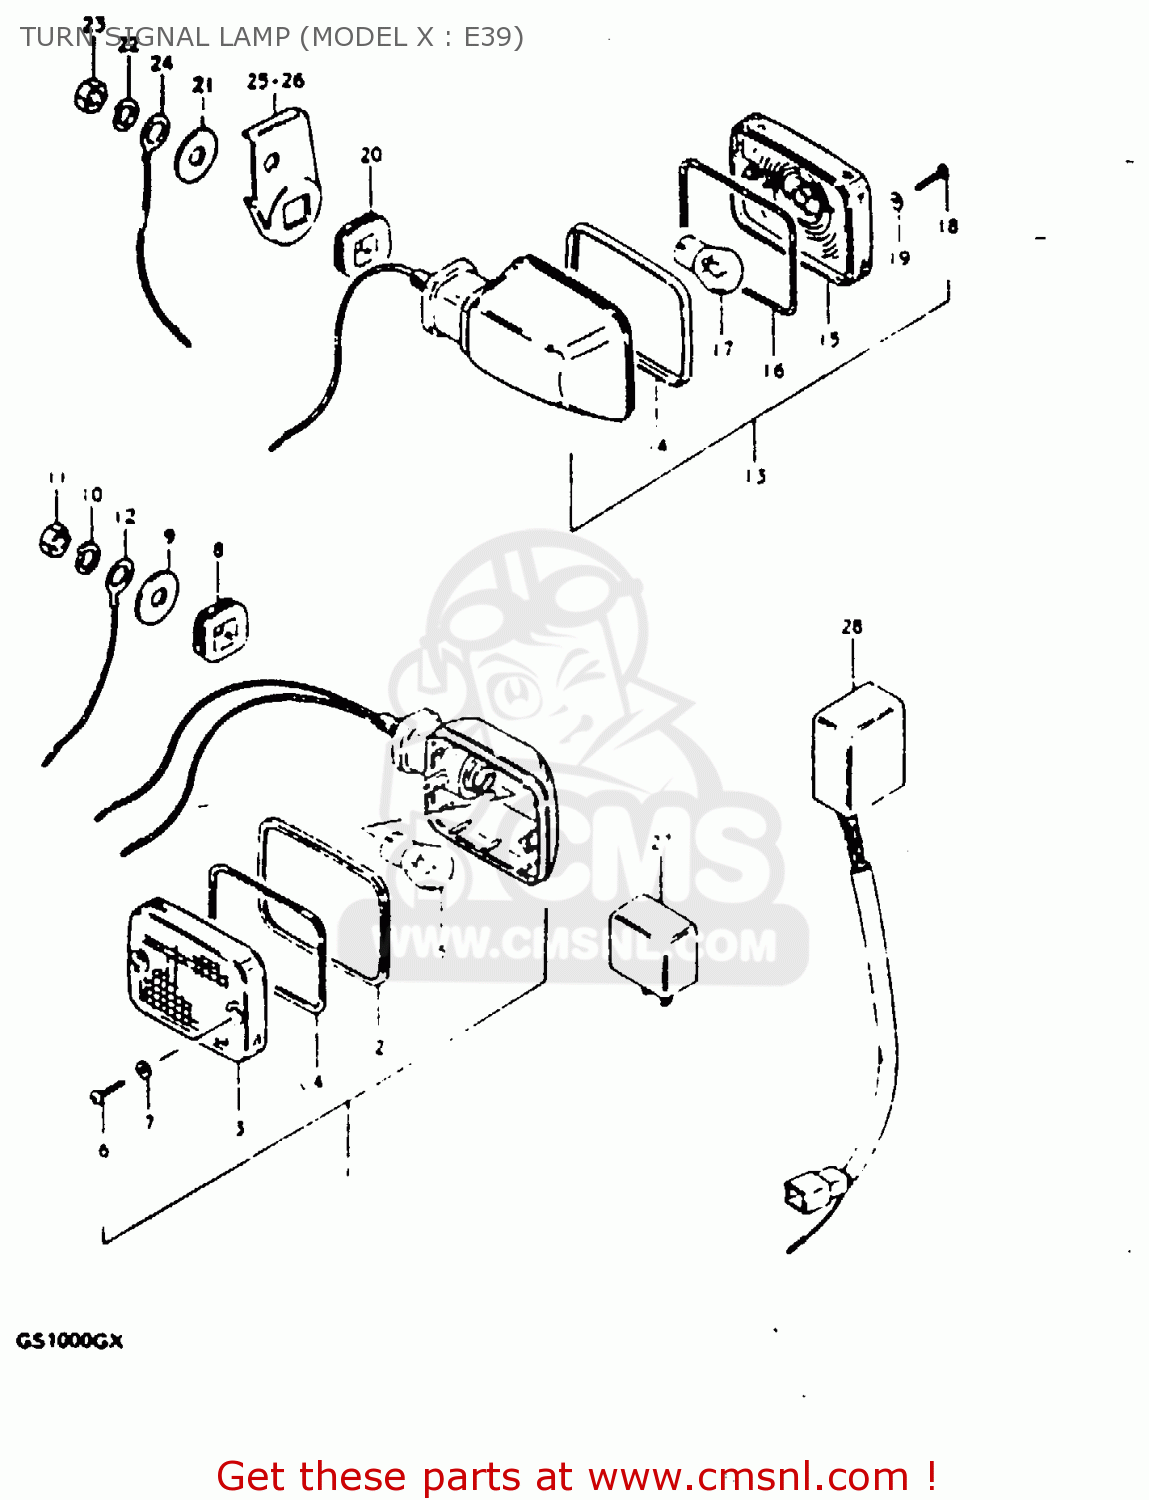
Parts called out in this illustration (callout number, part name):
1	LAMP, FRONT TURN SIGNAL
2	RIM
3	LENS
4	GASKET (NAS)
5	BULB 12V 21W
6	SCREW
7	GASKET (NAS)
8	CUSHION
9	WASHER (10.5X30X2.3)
10	LOCK WASHER
11	NUT
12	LEAD WIRE,EARTH
13	LAMP, REAR TURN SIGNAL
14	RIM
15	LENS
16	GASKET (NAS)
17	BULB 12V 21W
18	SCREW
19	GASKET (NAS)
20	CUSHION
21	WASHER (10.5X30X2.3)
22	LOCK WASHER
23	NUT
24	LEAD WIRE,EARTH
25	BRACKET,RR TURNSIGNAL LAMP,R
26	BRACKET,RR TURNSIGNAL LAMP,L
27	RELAY ASSY,TURNSIGNAL
28	UNIT,TURN SIGNAL CONTROL
